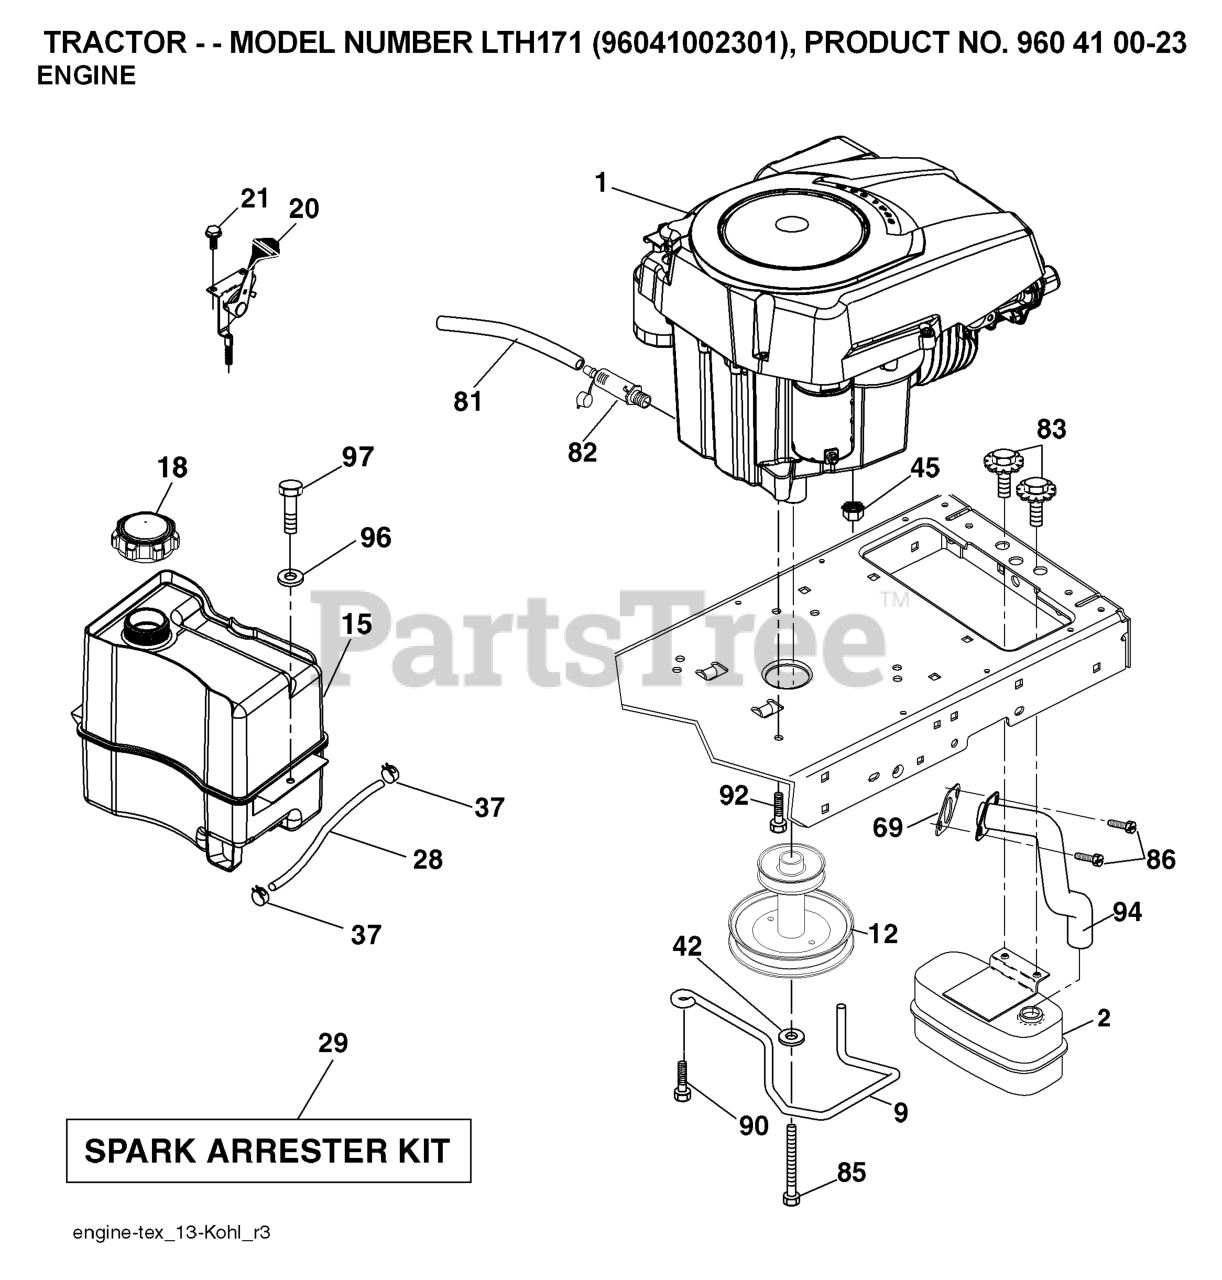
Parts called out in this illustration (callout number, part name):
1	HCS 3/8-24 X 2, GR8
2	SCREW, 1/4-20 X 3/8, SET
3	CLUTCH, WASHER
4	DECAL, ENGINE
5	BLADE ADAPTER
6	ENGINE PULLEY
7	BLADE DRIVER SPACER
8	BOLT 3/8-16 X 1 1/2, ZINC YELL
9	BLADE, 21" BR
10	KEY, STEPPED
11	OIL W/LABEL, QT
12	BRACKET-SHAFT SUPT
13	BEARING - SHAFT SUPPORT
14	DECK GUARD, BBC
15	SCREW #10-24 X 5/8
16	NUT 10-24 NYLOC
17	SLW 3/8 STD
